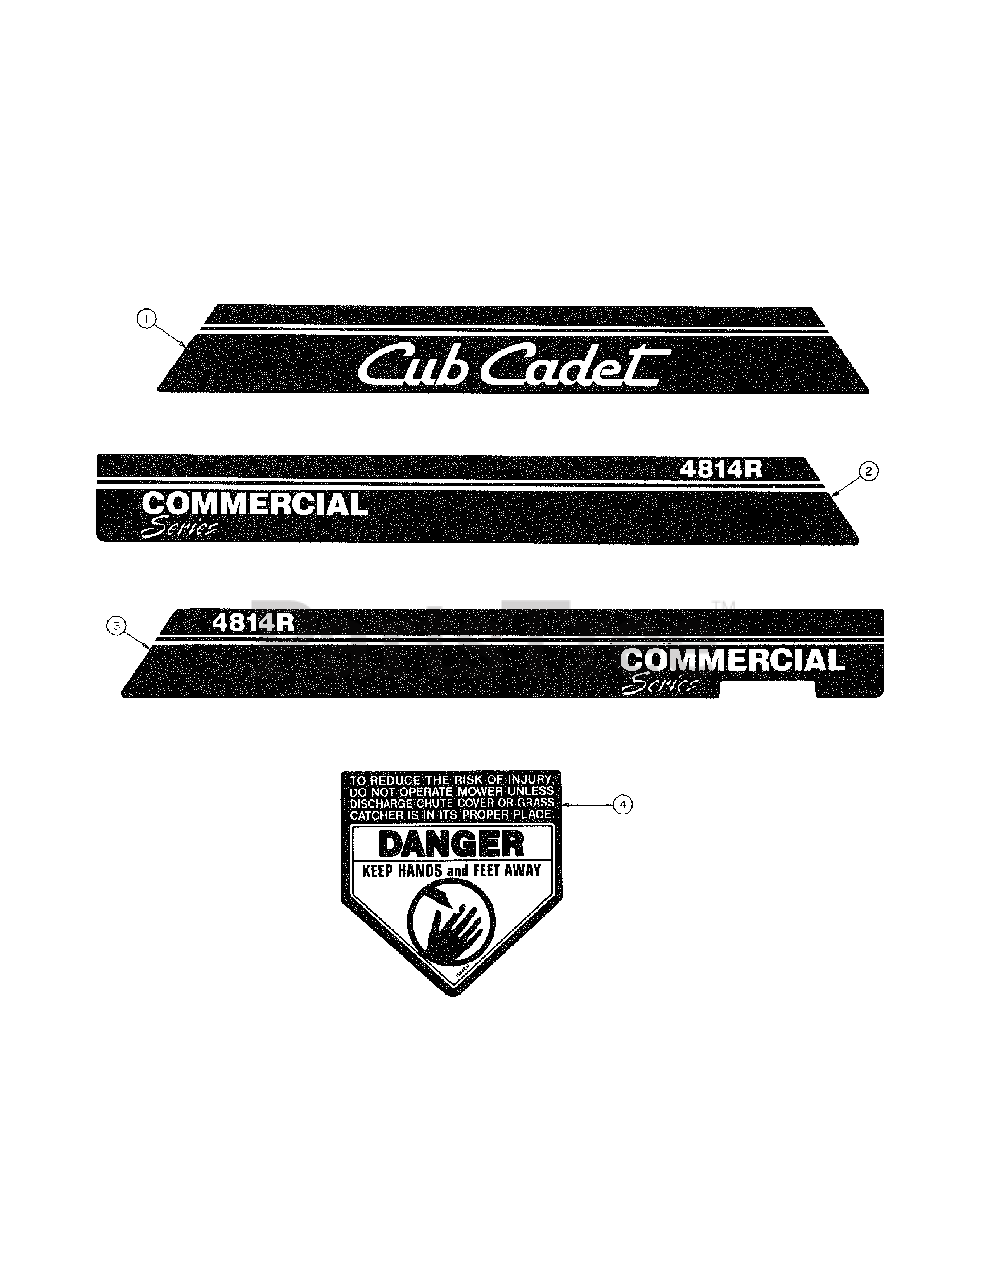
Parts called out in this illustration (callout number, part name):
1	Graphic, Belt Cover Front
2	Graphic, 4814R, Belt Cover RH
3	Graphic, 4814R, Belt Cover LH
4	Graphic, Danger Cut Finger
